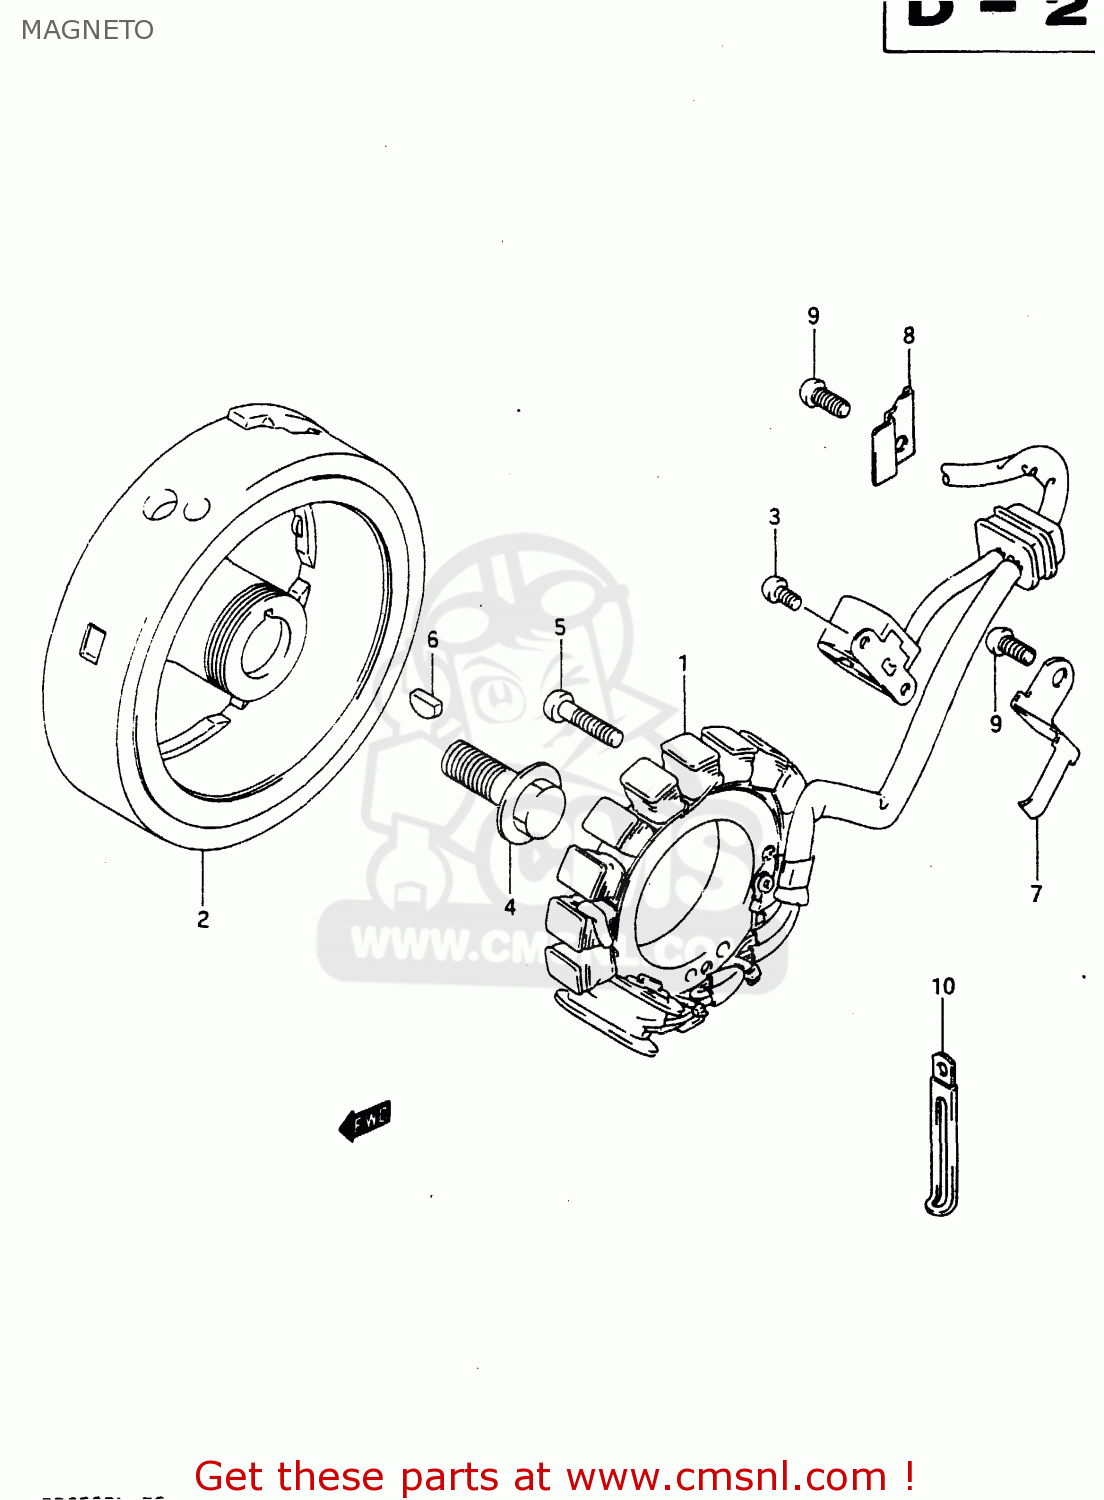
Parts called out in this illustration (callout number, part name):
1	STARTER ASSY
2	ROTOR
3	SCREW
4	BOLT(14X43)
5	SCREW
6	KEY 4MM
7	CLAMP,MAGNETO LEAD WIRE
8	CLAMP,MAGNETO LEAD WIRE
9	SCREW
10	CLAMP
